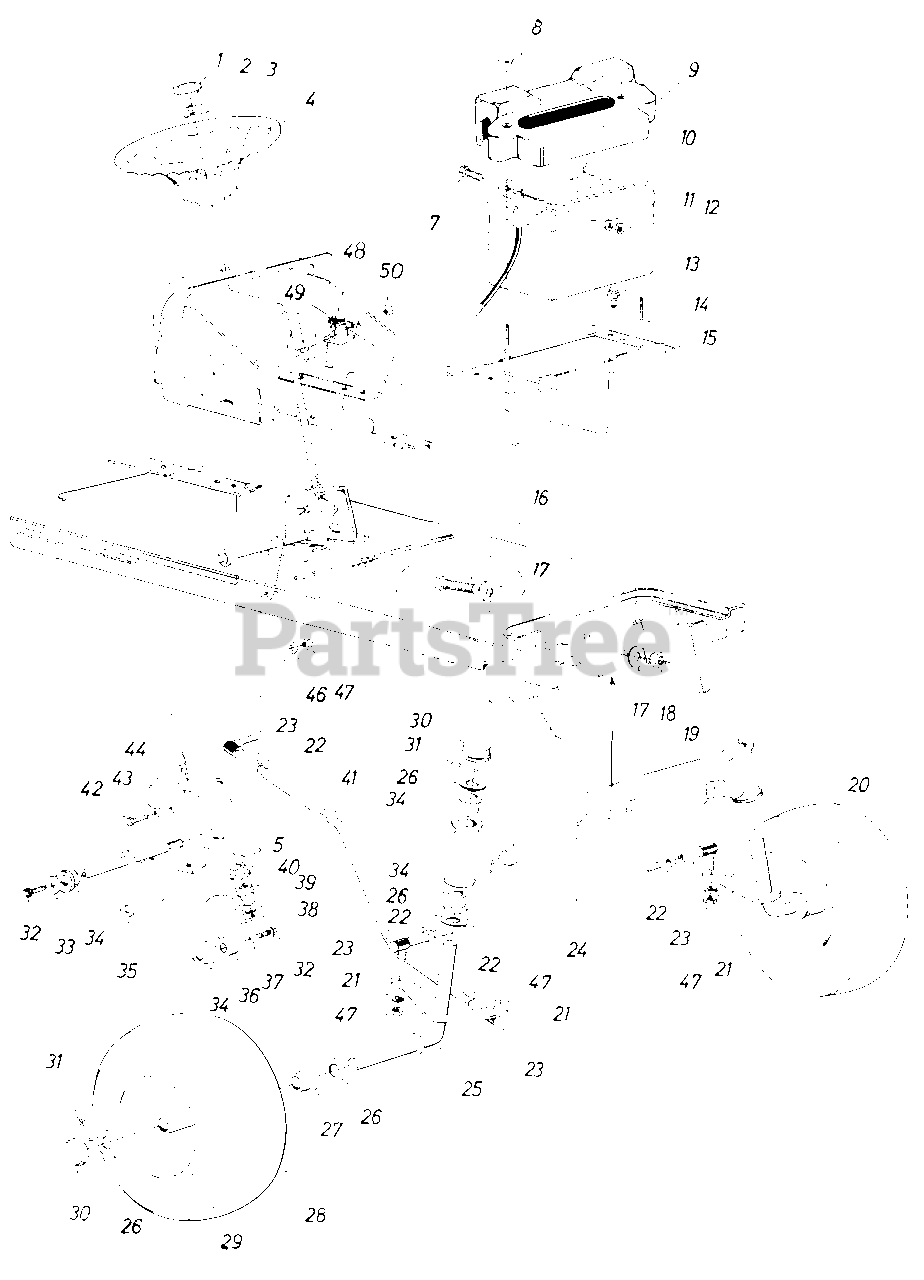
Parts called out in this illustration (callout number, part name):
1	Steering Wheel Cap
2	Hex Cent. L-Nut 5/16-24 Thd.
3	Bell-Wash. 5/16" I.D. x .87" O.D. x .060
4	Steering Wheel
5	Plastic Hex Bearing 5/8" I.D.
7	Hex Bolt 1/4-20 x .62" Lg.
8	Wing Nut Plastic 1/4-20 Thd.
9	Battery Cover
10	12-V Battery
11	L-Wash 1/4 " I.D.
12	Hex Nut 1/4-20 Thd.
13	Hex Thd. Rolling Scr. 1/4-20 x.50" Lg.
14	Battery Hold Down Rod
15	Battery Plate
16	Hex Bolt 5/8-18 x 2.5" Lg.
17	Flat Wash. .66" I.D. x 2.25" O.D. x .17
18	Hex Cent. L-Nut 5/8-18 Thd.
19	Front Pivot Bar Ass'y.
20	Front Axle Ass'y. L.H.
21	L-Wash. 3/8" I.D.
22	Hex Jam Nut 3/8-24 Thd.
23	Ball Joint Ass'y.
24	Tie Rod
25	Front Axle Ass'y. R.H.
26	Fl-Wash. .780 I.D. x 1.59 O.D.
27	Flange Bearing
28	Front Wheel Ass'y. Comp.
29	Front Wheel Rim Only
30	Dust Cover
31	Cotter Pin 5/32" Dia. x 1.00" Lg.
32	Hex Bolt 3/8-24 x .75" Lg. Grade 5
33	Fl-Wash. 3/8 I.D. x 1.25 O.D. x .090
34	Flange Double "D" Brg. .753 I.D.
35	Steering Arm Shaft Ass'y.
36	Side Gear Steering
37	Bell-Wash. 3/8" I.D.
38	Hex Cent. L-Nut 5/16-24 Thd.
39	Fl-Wash. 5/16" I.D. x .62 O.D. x .059
40	Pinion Gear Steering
41	Drag Link
42	Hex Nylon Scr. 3/8-16 x 1.25" Lg.
43	Hex Nut 3/8-16 Thd.
44	Steering Gear Sup. Ass'y.
46	L-Wash. 3/8" I.D.
47	Hex Nut 3/8-24 Thd.
48	Solenoid
49	Hex Bolt 1/4-20 x .5" Lg.
50	Hex Sems Nut 1/4-20 Thd.
